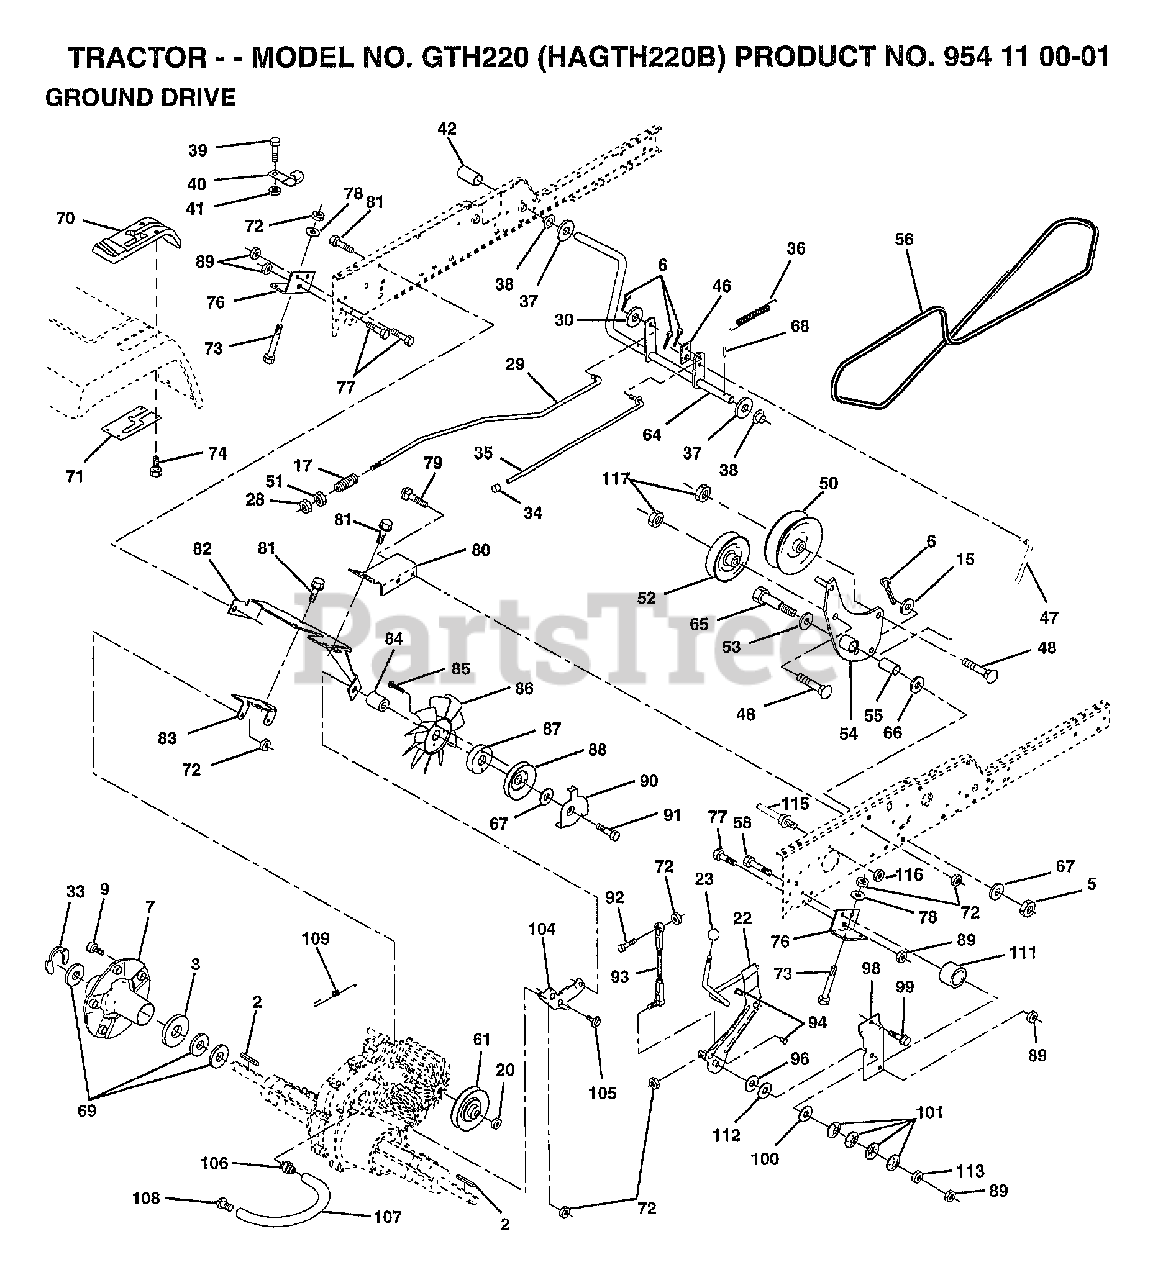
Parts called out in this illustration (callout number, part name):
5	NUT, CROWNLOCK 3/8-16
6	PIN COTTER 1/8 X 3/4 CAD
15	WASHER 13/32 X 13/16 X 16 GA
20	NUT, HEX JAM TOPLOCK 1/2-20
28	NUT HEX JAM 3/8-16 UNC
30	WASHER
32	NUT, HEX 7/16-14
39	SCREW, FIN #10-24 X 1
41	NUT, LOCK #10-24
48	BOLT, CARRIAGE 3/8-16 X 1-1/2 GR.5
51	LOCKNUT
58	BOLT, FIN HEX 7/16-14 X 1-1/2
67	WASHER
72	LOCKNUT
73	BOLT, FIN HEX 5/16-18 X 3
77	BOLT, FIN HEX 7/16-14 UNC X 1
78	WASHER, 11/32 X 3/4 X 12 GA.
79	BOLT, CARRIAGE 5/16-18 X 5/8
81	SCREW THDROL 3/8-16X3/4 TY-TT
85	SCREW, #10-24 X 1-1/4
89	NUT, CROWNLOCK 7/16-14
91	SCREW, THDROL 3/8-16 X 2-3/4
92	BOLT, HEX 5/16-18 X 1-1/4
99	SCREW, THDROL 3/8-16 X 1-1/2
105	SCREW, TAP 1/4-20 X 1/2
113	NUT, HEX 7/16-14
116	NUT, LOCK HEX FLANGE 5/16-18
117	NUT, LOCK FLG. 3/8-16 UNC
